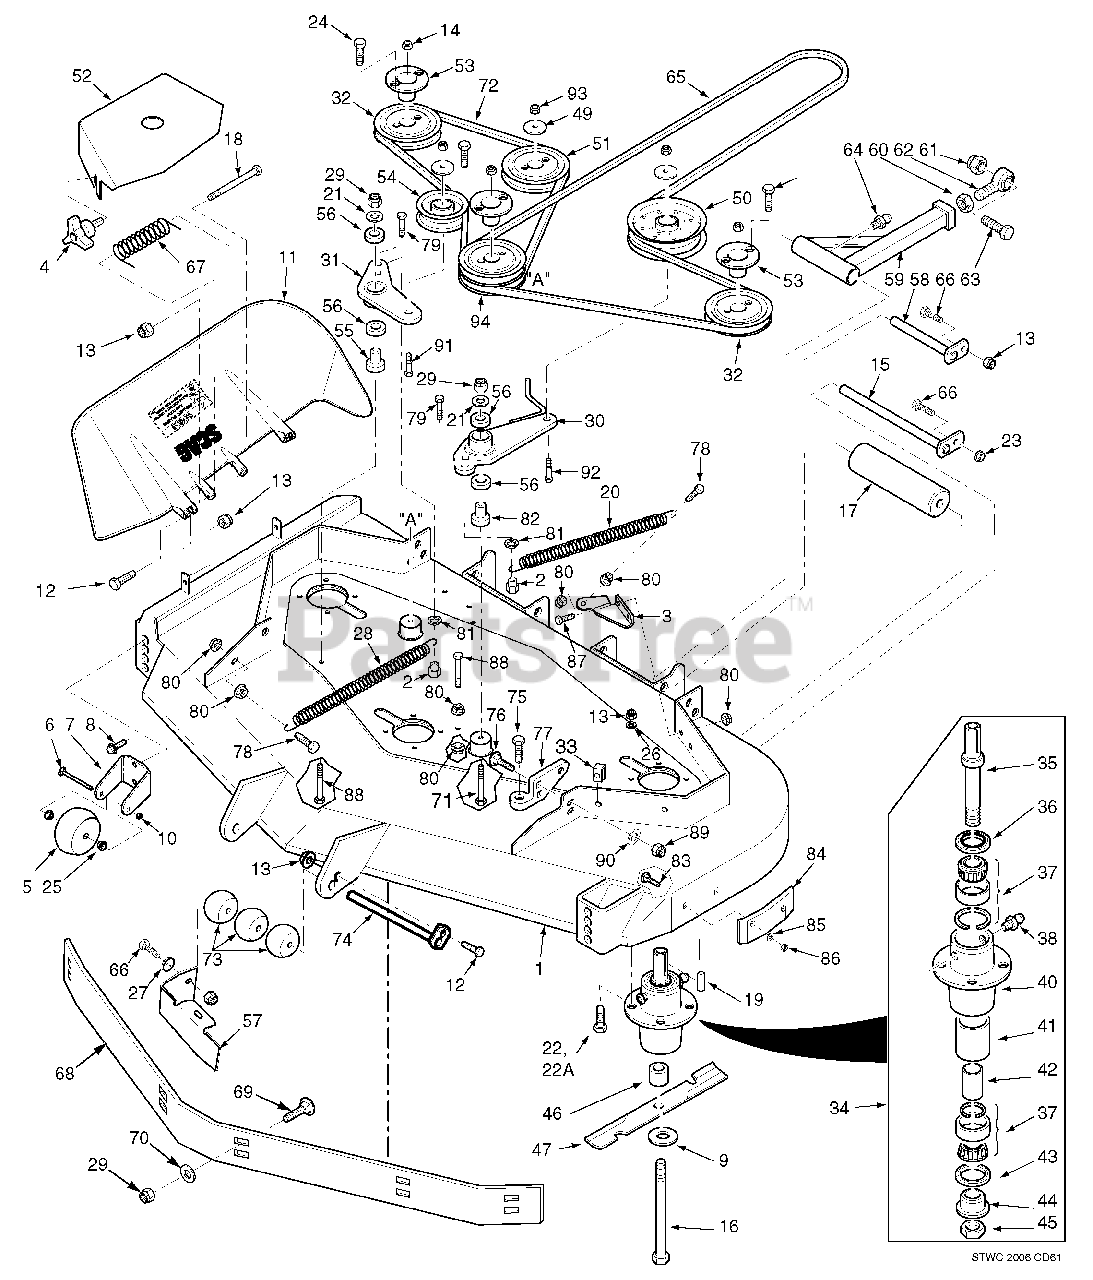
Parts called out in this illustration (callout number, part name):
1	Cutter Deck Velocity Plus
2	Boss, Spring Anchor
3	Bracket, LH Spring Anchor 61V
4	Wing Nut, 3/8-16
5	Anti-Scalp Wheel
6	Bolt, Carriage 3/8-16 x 4"
7	Bracket, Anti-Scalp Wheel
8	Bolt, Serr. Flng. 3/8-16 x 1"
9	Flatwasher, 5/8" Hardened
10	Locknut, 3/8-16 Center Lock
11	Discharge Chute
12	Bolt, Hex Hd. 5/16-18 x 1-1/2", Rear
13	Nut, Elastic Stop 5/16-18
14	Nut, 5/8-11 UNC
15	Shaft, Roller
16	Bolt, Hex Hd. 5/8-11 x 9-1/2"
17	Roller, Rear
18	Bolt, Hex Hd. 5/16-18 x 4-3/4"
19	Key, 1/4 x 1/4 x 2"
20	Spring, LH Deck Drive
21	Flatwasher, 3/8" (.938 x .391 x .105")
22	Bolt, Hex Hd. 5/16-18 x 1-3/4" Grd. 8
23	Nut, Serr. Flng. 5/16-18
24	Bolt, Hex Hd. 1/4-20 x 1" Grd. 8
25	Bushing, .376 ID Oilite(R)
26	Lockwasher 5/16"
27	Flatwasher 5/16"
28	Spring, RH Deck Drive
29	Nut, Elastic Stop 3/8-16
30	Idler Arm Assembly, LH Drive
31	Idler Arm Assembly, RH Drive
32	Pulley, Tapered Bore 6.33" Dia.
33	U-Nut, 3/8-16
34	Spindle Assembly
35	Shaft, Spindle
36	Seal Upper
37	Bearing Assembly
38	Grease Fitting
39	Valve, Grease Relief
40	Housing, Spindle
41	Spacer, Outside
42	Spacer, Inside
43	Seal, Lower
44	Bushing, Bottom
45	Nut, Special 1-1/16 - 18
46	Spacer, Spindle
47	Cutter Blade 21"
48	Pulley, Double Groove 6.33" Dia.
49	Dust Shield
50	Idler Pulley, 5" Dia.
51	Idler Pulley, 5" Dia.
52	Belt Cover (61V)
53	Hub, Tapered 1-1/8" Bore
54	Idler Pulley, 3-1/2" Dia.
55	Pivot, Idler
56	Bearing
57	Turbo Baffle, Bolt On
58	Push Arm Shaft
59	Push Arm
60	Nut, 5/8-18 UNF
61	Nut, Elastic Stop 5/8-11
62	Rod End, 5/8 Male RH Thread
63	Bolt, Hex Hd. 5/8-11 x 4-1/2"
64	Grease Fitting, 90 Degree
65	Belt, Deck Drive 61V
66	Bolt, Hex Hd. 5/16-18 x 1"
67	Spring, Discharge Chute
68	Baffle Weldment, 61V
69	Bolt, Carriage 3/8-16 x 1"
70	Flatwasher, 3/8 (.391 x .938 x .105")
71	Bolt, Hex Hd. 3/8-16 X 3-1/2"
72	Belt, Deck Drive RH
73	Wheel, Anti Scalp
74	Roller Shaft
75	Bolt, Special
76	Bolt, Carriage 7/16-14 x 1-1/4"
77	Lever Assy., Deck Level
78	Bolt, Hex Hd. 3/8-16 x 1-1/2" Grd. 8
79	Bolt, Hex Hd. 3/8-16 x 1"
80	Nut, Serr. Flng. 3/8-16
81	Lockwasher, 5/16"
82	Pivot, Idler Short
83	Bolt, Carr. 5/16-18 x 3/4"
84	Wear Pad
85	Flatwasher, 5/16 (.344 x .688 x .065")
86	Nut, Center Lock 5/16"
87	Bolt, Hex Hd. 3/8-16 x 1"
88	Bolt, Hex Hd. 3/8-16 x 2-1/2"
89	Nut, Elastic Stop 7/16-14
90	Flatwasher, 7/16 (.500 x 1.250 x .083")
91	Bolt, Hex Hd. 3/8-16 x 2-1/4"
92	Bolt, Hex Hd. 3/8-16 x 3"
93	Nut, Elastic Stop 3/8-16
94	Pulley, Double Groove 6.33" Dia.
